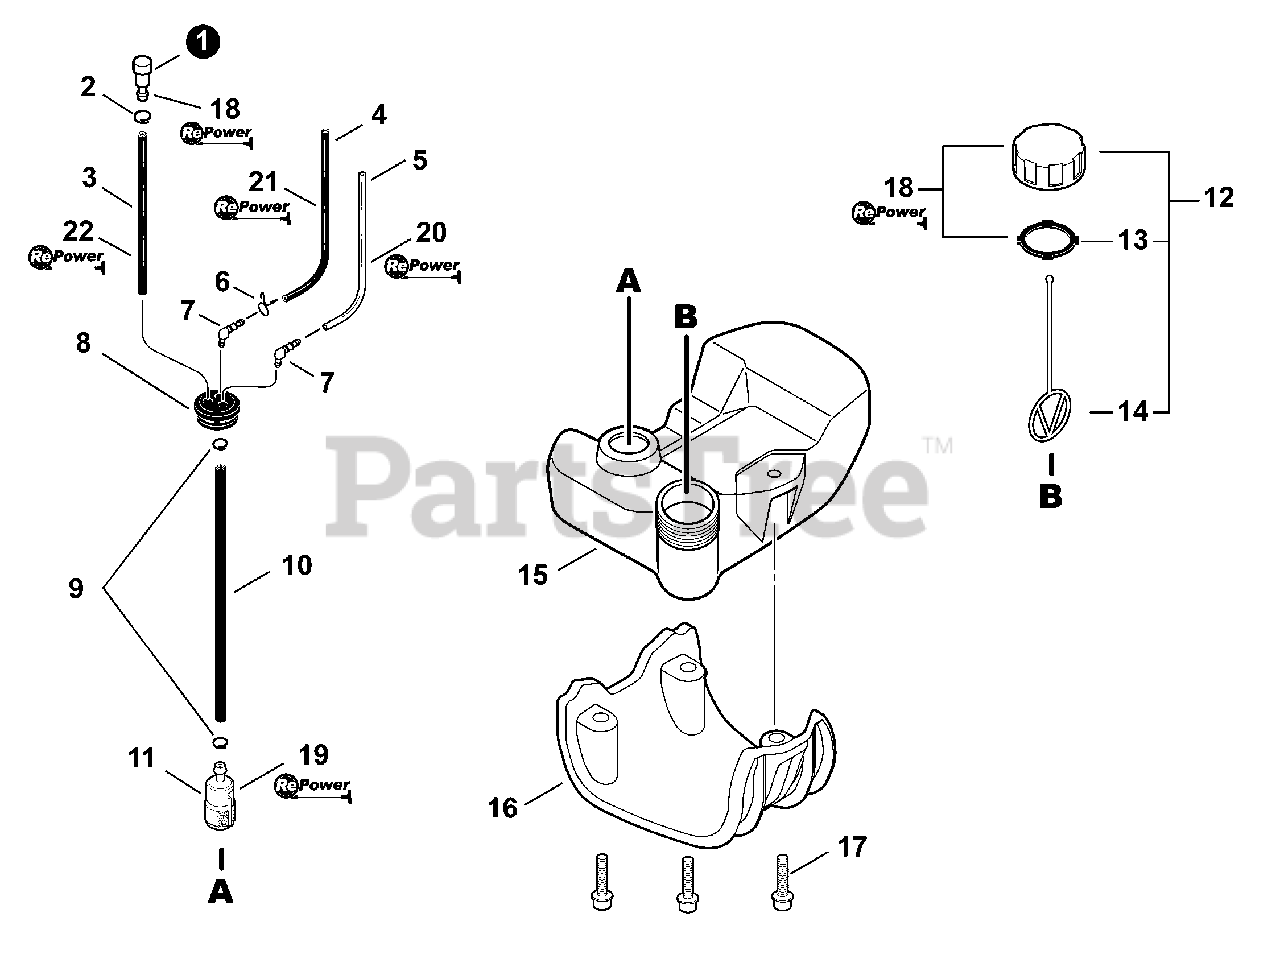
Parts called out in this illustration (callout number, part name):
1	VENT ASSY
2	CLIP 6.5 MM
3	PIPE 3×6×115 BLACK
4	PIPE, FUEL 3×5×87 BLACK
5	PIPE, FUEL 3×6×80 CLEAR
6	CLIP, SPRING Ø5.2
7	CONNECTOR, PIPE
8	GROMMET, FUEL
9	CLIP Ø6
10	PIPE, FUEL - 3×5×125 - BLACK
11	FILTER, FUEL 125-528
12	CAP ASSY, FUEL
13	GASKET, FUEL CAP
14	CONNECTOR, CAP L= 100 MM
15	TANK, FUEL
16	GUARD, FUEL TANK
17	BOLT 5×20
18	CAP/VENT KIT - REPOWER
19	TUNE-UP KIT - REPOWER
20	BULK PIPE - 3×6 MM CLEAR (4 PIECES×2 M)
21	BULK PIPE - 3×5 MM BLACK (4 PIECES×2 M)
22	BULK PIPE - 3×6 MM BLACK (4 PIECES×2 M)
